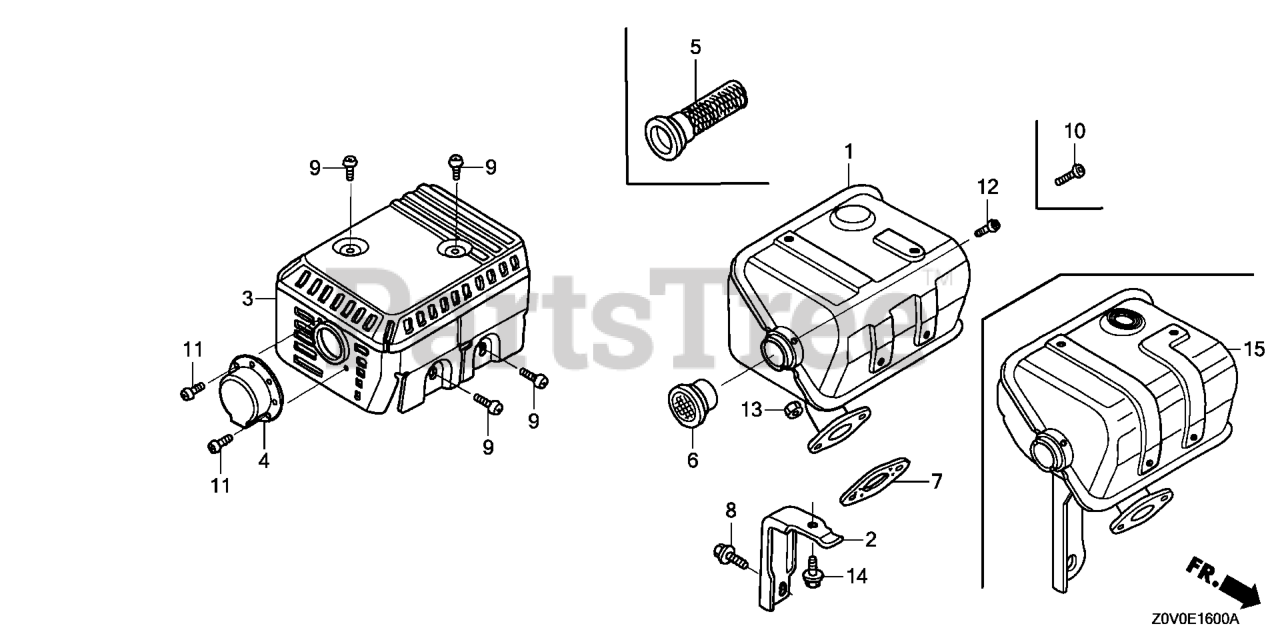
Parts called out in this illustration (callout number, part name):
3	PROTECTOR, MUFFLER
5	ARRESTER, SPARK
7	GASKET, MUFFLER
8	BOLT, FLANGE (6X13)
9	SCREW, TAPPING (5X8)
10	SCREW, TAPPING (4X6) (TO INSTALL OPTIONAL SPARK ARRESTER)
13	NUT, HEX. (8MM)
15	MUFFLER
